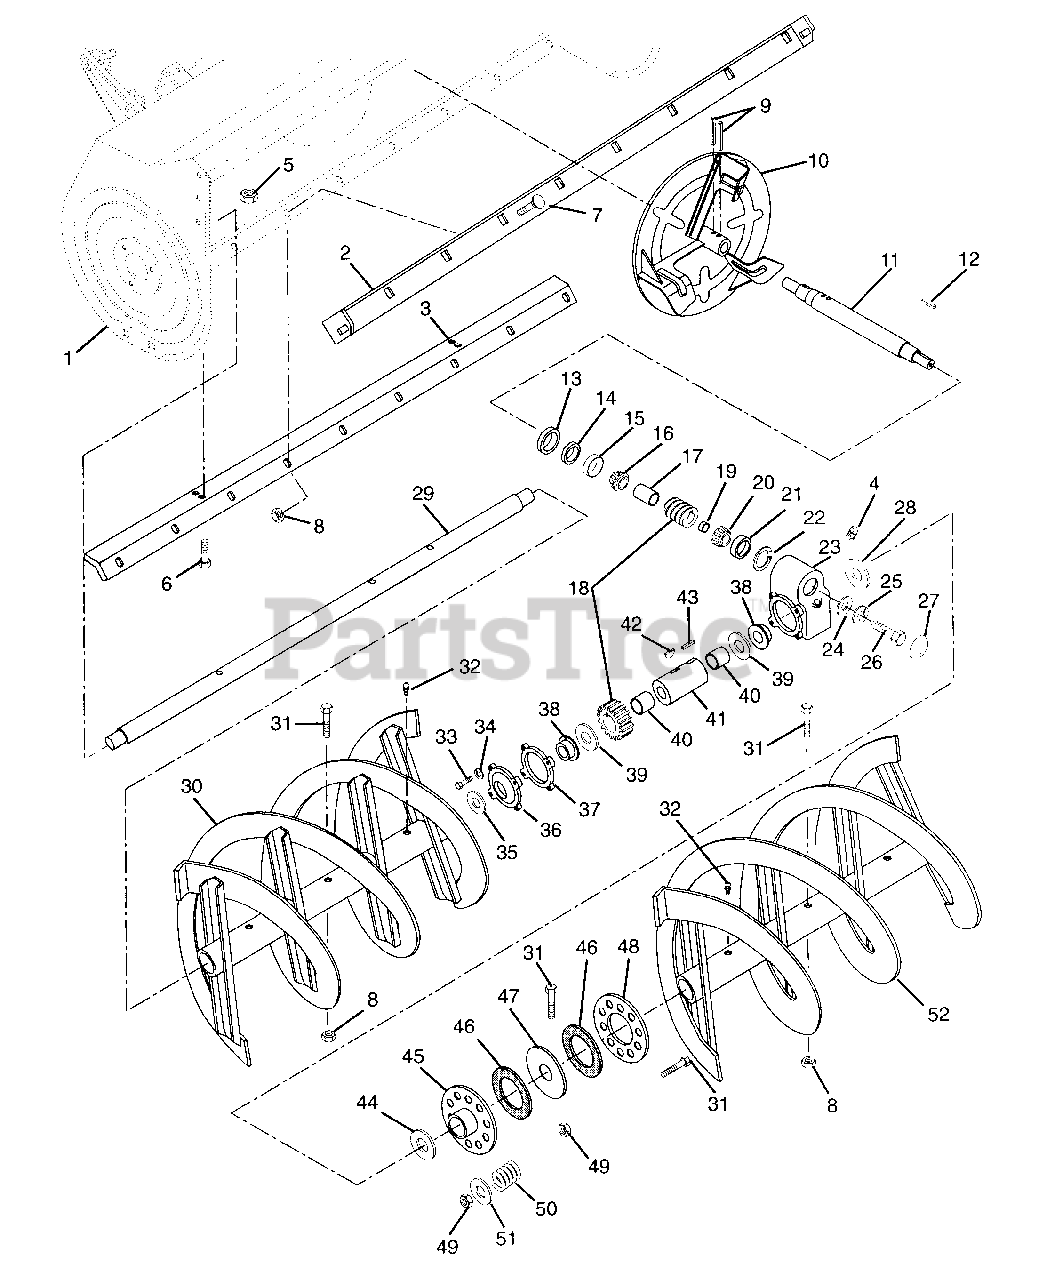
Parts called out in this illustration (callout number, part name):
1	48 AUGER/16 IMPELLER HOUSING
2	SCRAPER BLADE
3	SCRAPER BLADE BRACE (A)
4	PIPE PLUG
5	@NUT-LK-CTR .38-16 YWZC
6	@BLT-HEX .38-16X.75 GR5 YWZC
7	BLT-RDHDSQSHK.31-18X.75 GR2 YW
8	@NUT-LK-CTR .31-18 YWZC
9	PIN-ROLL .313X1.75
10	FAN 16 INCH
11	WORM SHAFT
12	KEY-SQ .188X1.0X.188 SAE 8630
13	ADJUSTMENT PLUG
14	SEAL 1.125X1.375X.125
15	BRG-CUP1.980X.420
16	BRG-CONE 1.0X.58
17	BEARING SPACER 1.032X1.25X1.78
18	WORM & GEAR SERVICE ASSEMBLY
19	BSHG, SPCR .755X1.12X.50 PM
20	BRG-CONE .750X.61
21	BRG-CUP 1.781X.475
22	RG-RTNG-INT 1.781X.062
23	GEAR CASE - CAST IRON
24	WSHR-FL-STL .328X1.0X.094 YWZC
25	@WSHR-LK .31X.078 REG YWZC
26	@BLT-HEX .31-18X.75 GR5 YWZC
27	DUST CAP
28	SEAL 1.625X2.125X.250
29	48 INCH RAKE SHAFT
30	RAKE, RIGHT-48(1.12ID X 15.75)
31	@BLT-HEX .31-18X2.00 GR5 YWZC
32	FTG-LUBE .25-28X.256 YWZC
33	@BLT-HEX .25-20X.75 GR5 YWZC
34	@WSHR-LK-EXT.262X.502X.026YWZC
35	SEAL 1.625X2.125X.250
36	GEAR CASE COVER
38	BSHG-FLG .683X1.87X1.68X2.250
39	WSHR-FL-STL 1.625X2.500X.012
40	BSHG-SLV 1.125X1.250X1.000
41	GEAR CASE SHAFT
42	KEY-FTHR .25X.875X.25 SAE 8630
43	KEY-SQ .25X.625X.375
44	WSHR-FL-NYL 1.625X2.500X.060
46	FRICTION DISC
47	DRIVEN PLATE
48	PRESSURE PLATE
49	@NUT-LK-CTR .31-18 YWZC
50	SG-COMP .156X.665X.75
51	@WSHR-FL-STL.344X.688X.065YWZC
52	RAKE, LEFT-48"(1.12ID X 15.75)
